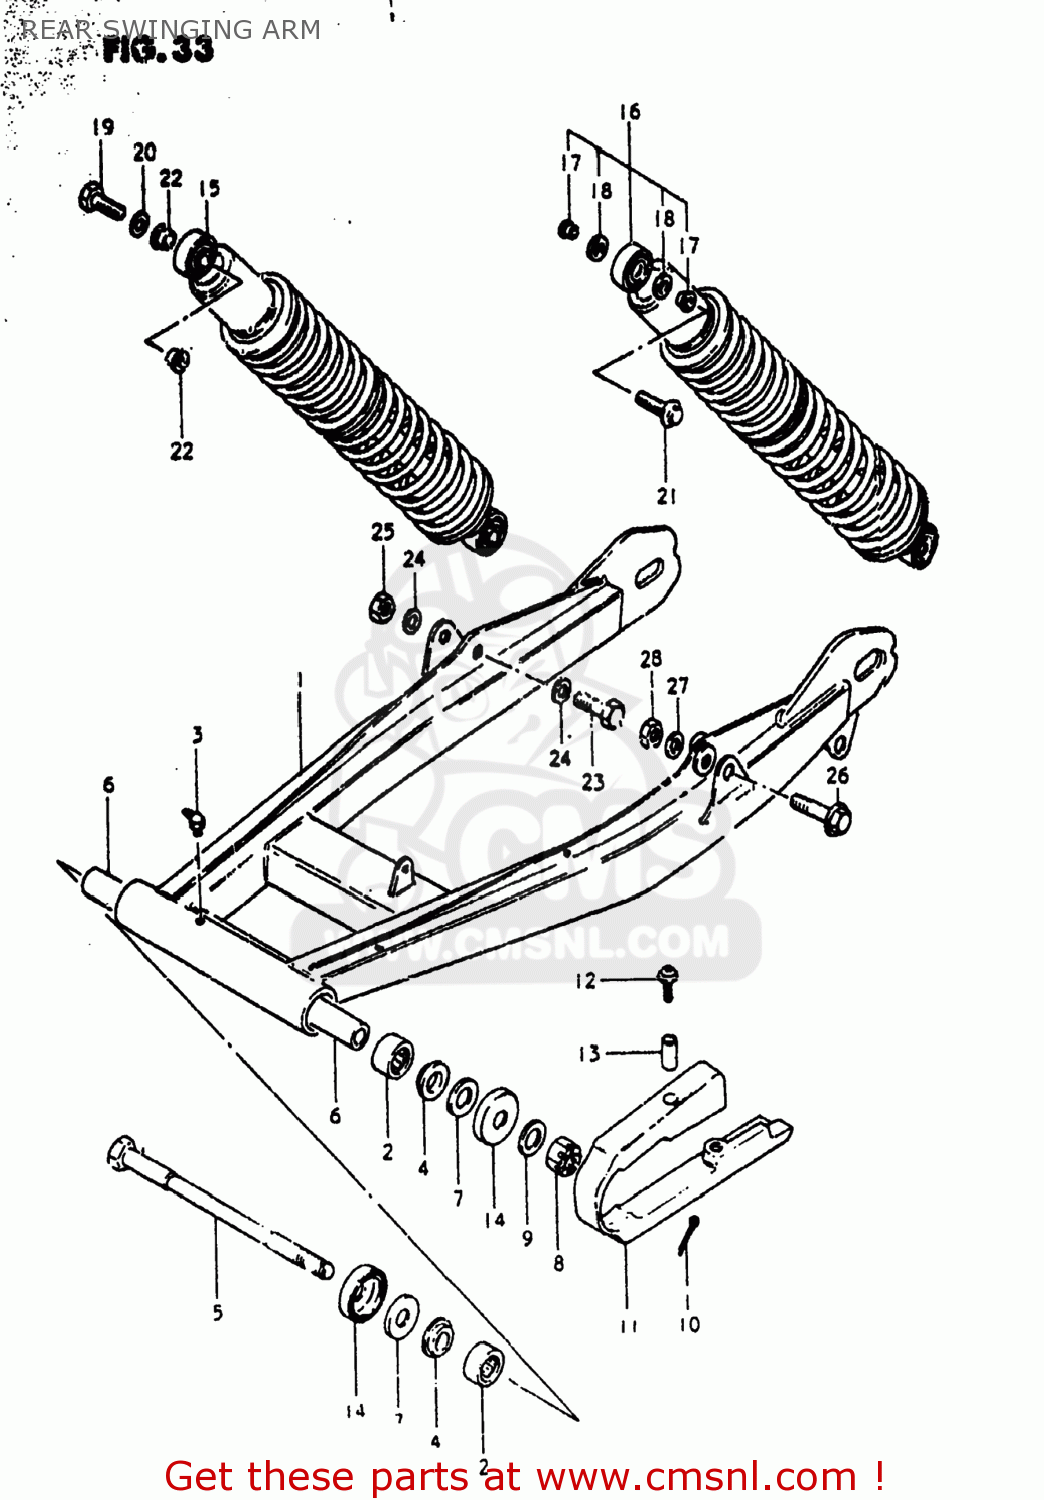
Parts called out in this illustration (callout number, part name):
1	SWING ARM ASSEMBLY,REAR
2	BEARING
3	NIPPLE,GREASE
4	BUSHING,REAR SWING ARM PIVOT
5	SHAFT,REAR SWING ARM
6	SPACER,REAR SWING ARM
7	WASHER
8	NUT 14MM
9	WASHER
10	COTTER PIN
11	BUFFER,CHAIN TOUCH DEFLECTOR
12	SCREW,CHAIN TOUCH DEFEND
13	SPACER (5.5X8X4)
14	COVER,RR SWGARM DUST SEAL
15	ABSORBER ASSEMBLY,REAR SHOCK
16	ABSORBER ASSEMBLY,REAR SHOCK
17	SPACER,REAR SHOCK ABSORBER
18	DUST SEAL,REAR SHOCK
19	BOLT
20	WASHER
21	BOLT 10X40
22	SPACER,RR SHK ABS INNER
23	BOLT(8X46)
24	WASHER
25	NUT
26	BOLT(10X52)
27	WASHER
28	NUT
